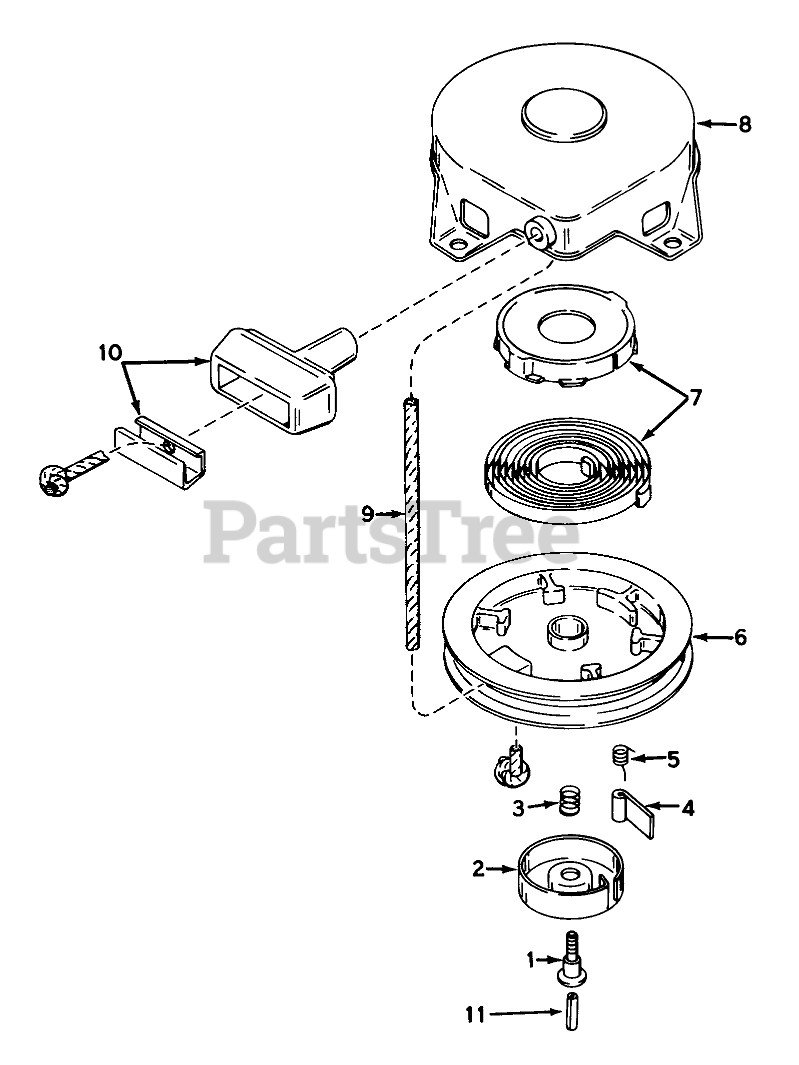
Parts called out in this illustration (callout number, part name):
2	Retainer
3	Spring-Brake
4	Dog-Starter
5	Spring-Dog
7	Spring & Keeper Assy
8	Housing Assy., Starter (Incl. Ref. #1)
9	Rope-Starter
10	Assy., Starter
11	Centering
